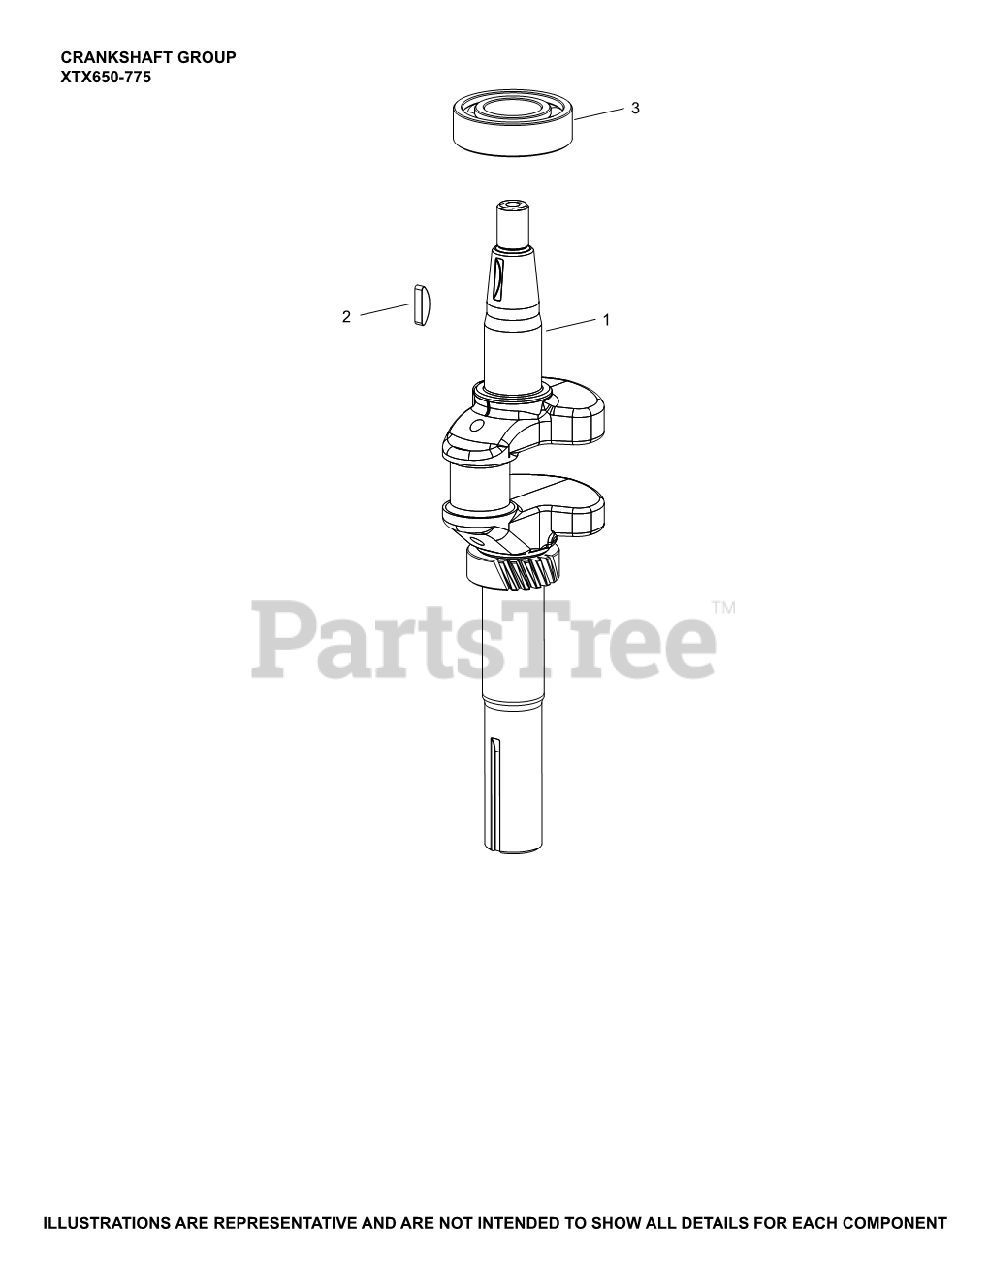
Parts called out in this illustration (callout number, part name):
1	CRANKSHAFT ASSEMBLY
2	KEY, FLYWHEEL
3	BEARING, BALL
